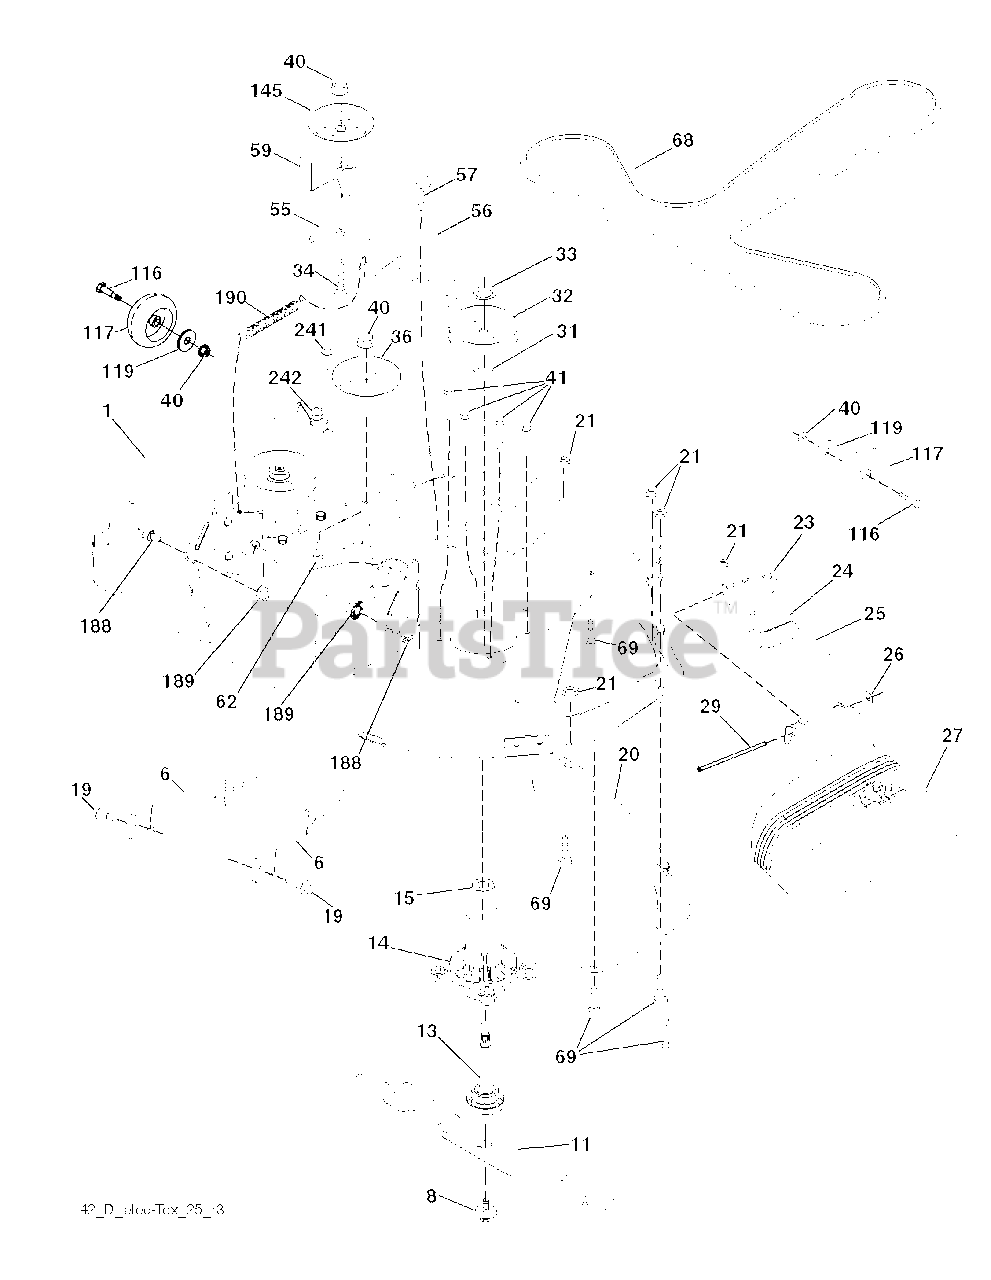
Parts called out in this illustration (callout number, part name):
1	DECK.WELDMNT.42"GREYMS498
6	ARM.SUSPENSION.MOWER.R
8	BOLT.WASHER.ASM.7/16-2
11	42" HI-LIFT BLADE
13	SHAFT.ASM.MDRL.N/GREASE.38
14	HOUSING.MANDREL.4PT.
19	BOLT.SHOULDER
20	BAFFLE.VORTEX
21	LOCKNUT
23	BRKT.DEFLECTOR.38"2005+
24	CAP-SLEEVE LT
25	SPRING.TORSION.DEFLECT
26	NUT PUSH M
27	SHIELD.DEFLECTOR.MOWER.42"BLAC
29	ROD.HINGE
31	WASHER.SPACER.MANDREL
32	PULLEY/MANDREL
33	NUT.FLANGE.LOCK.TOP
34	BOLT.3/8-16X1.50
36	PULLEY.IDLER.2006
40	NUT LOCK FLG 3/8-16 UNC
41	BOLT.HEX.WASHR.HED.313-18X1.19
55	IDLER.ARM.42"
56	SPACER.RETAINER
57	SCREW 3/8-16X1
59	GUARD, BELT
68	BELT V SECONDARY
69	BOLT
116	BOLT M
117	WHEEL.GAGE.HALF.SPOKED
119	WASHER
145	PULLEY.IDLER.48"PRIMARY
188	STUD.FASTNER.W/ANTI-ROTATE
189	NUT LOCK HEX FLANGE 5/16-18
190	SPRING.MOWER.DRIVE.ELECTRIC
241	SCREW.TT.#10-32X.5.3/8.FLANGE
242	PORT.WASHOUT
